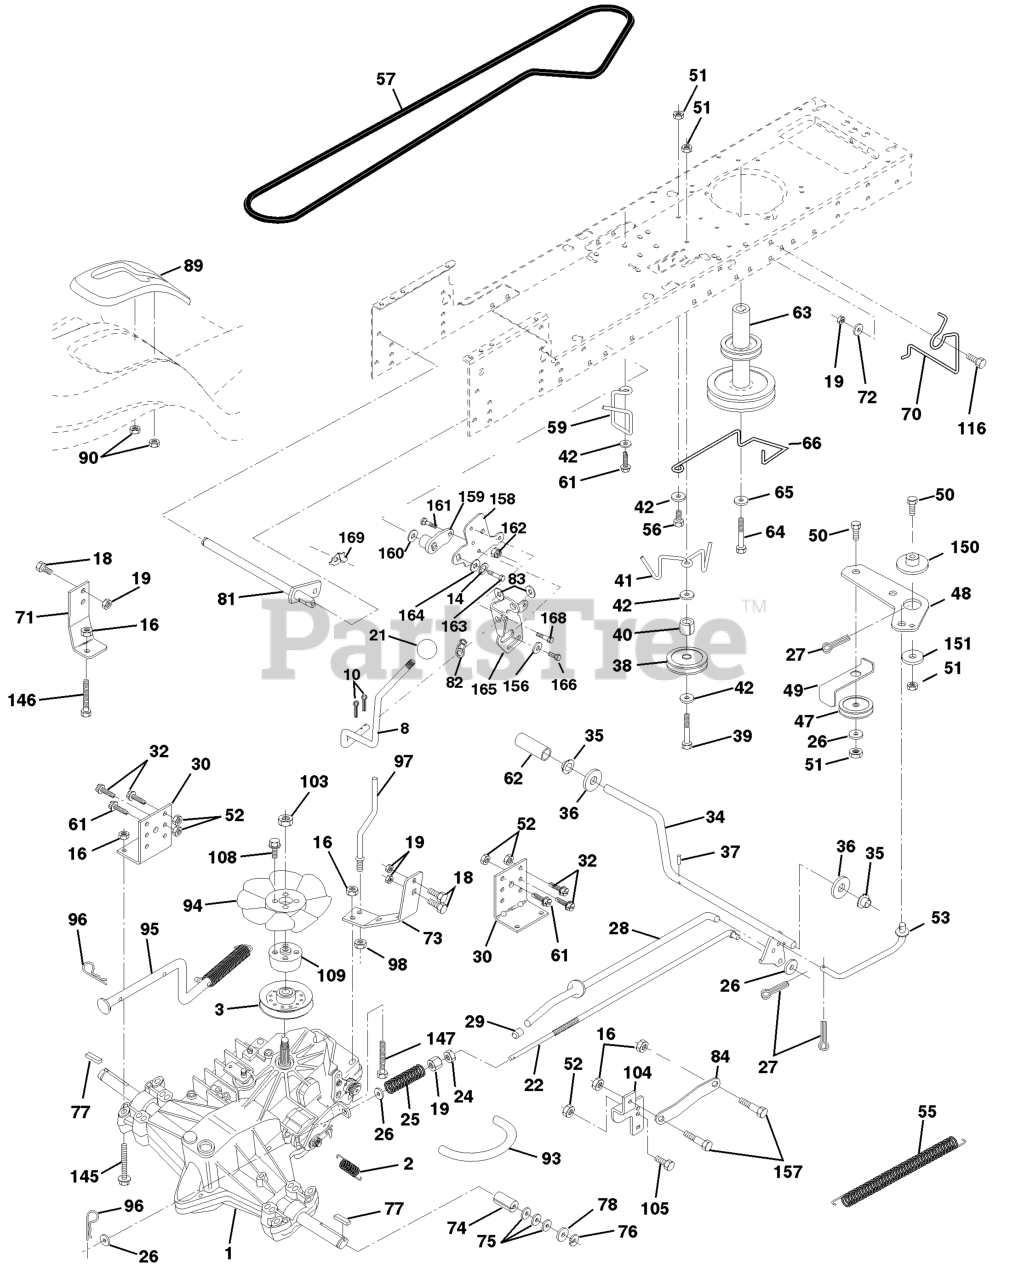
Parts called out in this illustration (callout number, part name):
2	SPRING BRAKE
3	PULLEY.4.20.HYDRO
8	ROD SHIFT FENDER ADJUST STLT
10	PIN COTTER
14	LOCKWASHER
16	NUT.71038.31-18.HEX.NYLOCK
18	BOLT
19	NUT
21	KNOB.DUCKHEAD.1/2
22	ROD BRAKE HYDRO
24	NUT
25	SPRING ROD LT
26	WASHER
27	COTTER PIN
28	ROD BRAKE PARK LT
29	PLUNGER CAP
30	BRACKET TRANSAXLE
32	BOLT
34	SHAFT, FOOT PEDAL
35	BEARING.NYLON
36	WASHER LT
37	DRIVE PIN
38	FLAT IDLER PULLEY
41	KEEPER.BELT.IDLER.FLAT
42	WASHER
47	IDLER PULLEY
48	BELLCRANK, CLUTCH
49	RETAIN BELT
50	BOLT
52	LOCKNUT
53	LINK, CLUTCH LT
55	SPRING, RETURN LT
59	KEEPER CENTER SPAN
61	SCREW
62	PEDAL COVER T
63	PULLEY.ENG.CL.MECH.SLVR.LT/YT
64	BOLT
65	LOCKWASHER
66	KEEPER BELT ENGINE
70	KEEPER BELT ENG
71	STRAP TORQUE LH HYDRO
72	WASHER
73	STRAP TORQUE RH HYDRO
74	SPACER SPLIT
77	SQUARE KEY
81	Shaft Asm Cross Tapered
82	SHIFT SPRING
83	WASHER
84	Link Transaxle
89	SHIFT CONSOLE
90	NUT.PUSH.3/16
93	LINE FUEL HYD 4"
94	FAN 7" HYDRO
95	CONTROL ARM, BYPASS HYDRO
96	RETAINER M
97	KEEPER BELT RH
103	NUT.HEX.1/2-20
104	ARM, CONTROL HYDRO
109	ADAPTOR FAN HYDRO
116	BOLT
145	BOLT
146	Bolt Hex Flghd 5/16-18 x 2-1/4
147	Bolt Hex Flghd 5/16-18 x 1-1/2
150	BUSHING.BELLCRANK.GRD.DR
151	WASHER 12/32X2X10GA
156	WASHER.SRRTD.5/16
157	BOLT SHOULDER 5/16-18
158	BRACKET
159	HUB
160	Washer 29/32 x 1-1/4 x 16 Ga.
161	BOLT
162	NUT.CROWNLOCK.1/4
163	BOLT
164	Washer 5/8 x .281 x 10 Ga.
165	RP BRACKET
168	BOLT.SHOULDER.5/16-18X
169	PLATE.FASTENING.CROSS.SHAFT
